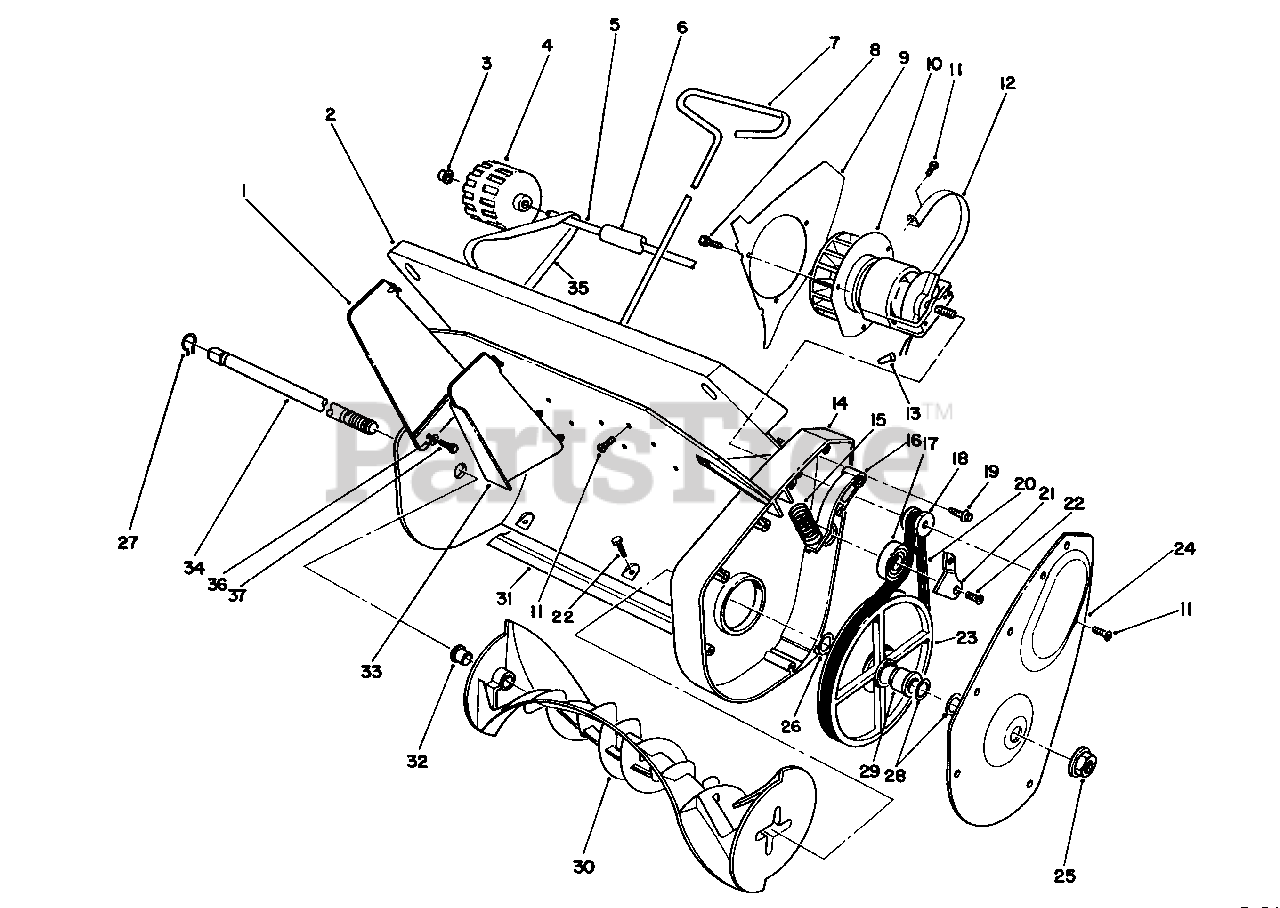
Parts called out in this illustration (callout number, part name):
1	Vane-Outer
2	Mount-Vane
3	Nut-Push On
5	Shaft-Axle
6	Sleeve-Axle
7	Rod-Vane Adjustment
8	Screw-Self Tapping
9	Baffle-Air
11	Screw-Self Tap. Pan Hd.
12	Mount-Motor
13	Connector-Wire
15	Spring-Compression Idler
16	Arm-Idler
17	Bearing-Ball
18	Pulley-Drive
19	Screw-Hex. Washer Hd.
20	Belt-Drive
21	Retainer-Idler Pulley
22	Screw-Self Tap. Pan Hd.
23	Pulley-Driven
24	Cover-Belt Case
25	Nut-Flange Lock
26	Washer-Thrust
27	Ring-Retaining
28	Washer-Thrust
29	Bushing-Rotor
32	Bushing-Rotor
33	Vane-Center
34	Shaft-Rotor
35	Bracket-Wheel R.H.
37	Screw-Self Tapping
